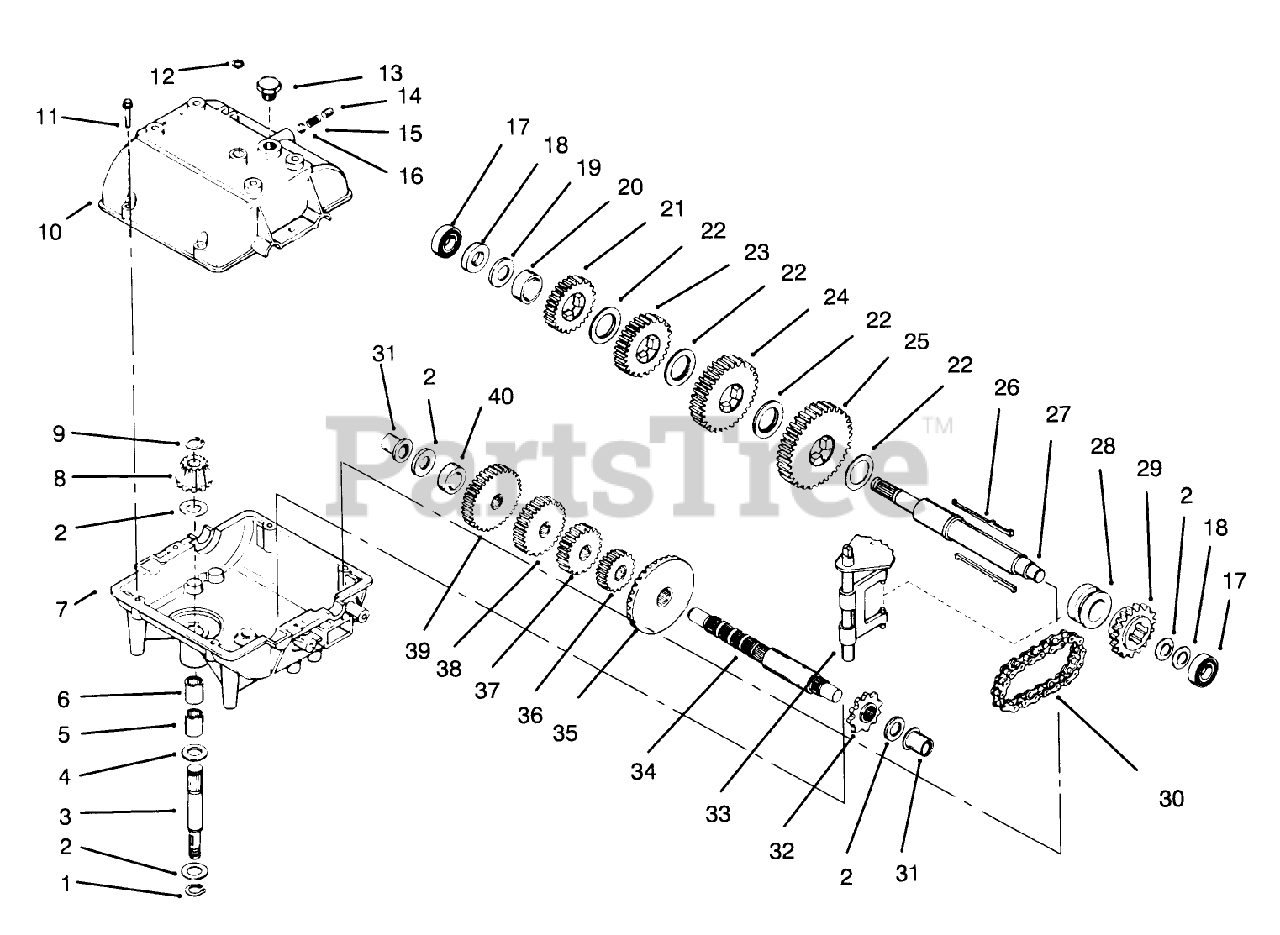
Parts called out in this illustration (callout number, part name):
1	Ring-Snap
2	Washer
3	Shaft-Input
4	O Ring
5	Bearing-Needle
6	Bearing-Needle
7	Case-Transmission
8	Bevel Pinion-Input
9	Ring-Retainer
10	Cover-Transmission
11	Ring Set (.020 O S)
12	Cut Seal-Square
14	Screw-Set
15	Spring
16	Ball-Steel
17	Bearing-Ball
18	Thrust Washer
19	Washer
20	Spacer
21	Gear-Spur, 25 Teeth
22	Washer
23	Gear-Spur 27 Teeth
24	Gear-Spur, 30 Teeth
25	Gear-Spur, 35 Teeth
27	Shaft-Output/Brake
28	Collar-Shift
29	Sprocket-18 Teeth
30	Chain-Roller #41
31	Bushing-Flange
32	Sprocket-9 Teeth
33	Rod and Fork ASM
34	Countershaft
35	Gear-Bevel, 42 teeth
36	Gear-Spur 15 Teeth
37	Gear-Spur, 20 Teeth
38	Gear-Spur 23 Teeth
39	Gear-Spur, 25 Teeth
40	Spacer
